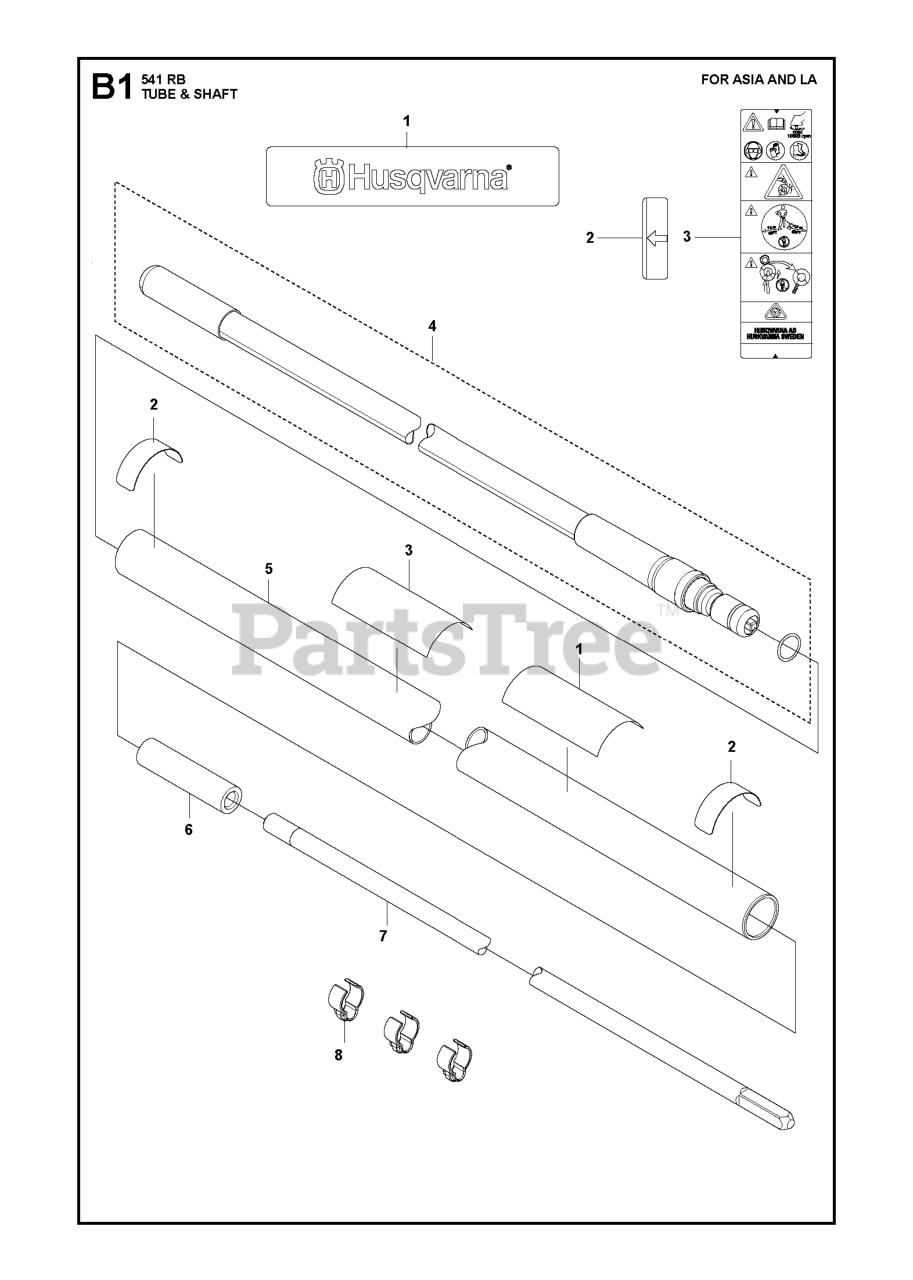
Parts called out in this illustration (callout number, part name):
2	LABEL
5	PIPE COMP.(RPLS T321712100)
8	CLAMP
